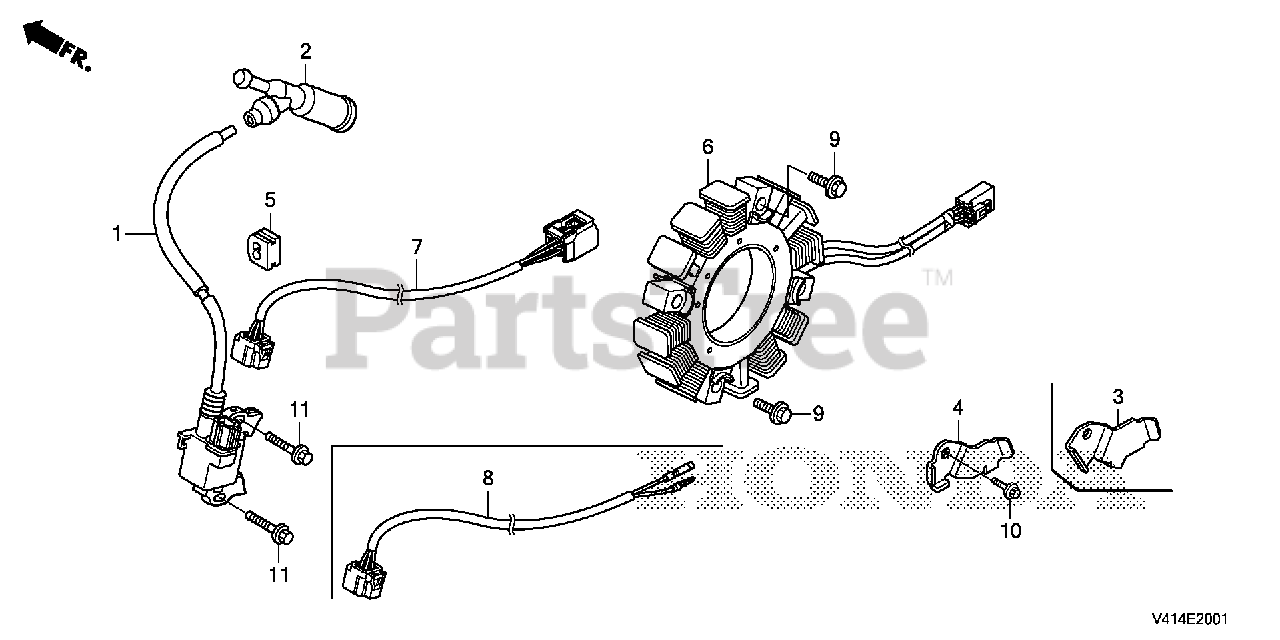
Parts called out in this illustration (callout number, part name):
1	COIL ASSY., IGNITION
2	CAP ASSY., NOISE SUPPRESSOR (NGK Y-EZD)
3	CLAMP, WIRE
5	GROMMET, WIRE
6	COIL ASSY., CHARGE
7	WIRE HARNESS ASSY., ENGINE
9	BOLT, FLANGE (6X40) (CT200)
10	BOLT, FLANGE (6X12) (CT200)
11	BOLT, FLANGE (6X28) (CT200)
